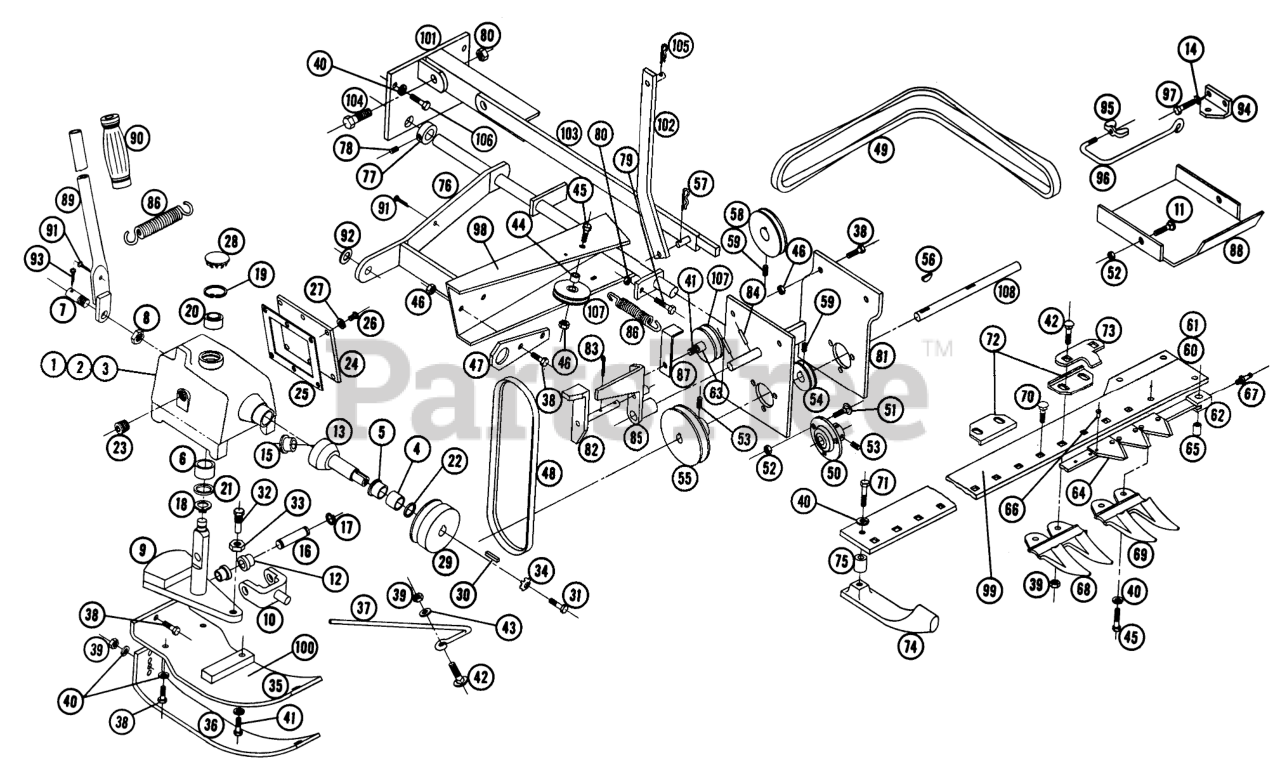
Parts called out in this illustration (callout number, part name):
1	Ass-y Housing Complete-Sickle Drive
2	Ass-y Housings & Bearings
3	Housing
4	Bearing-Bronze Sleeve
5	Bearing-Bronze Sleeve
6	Bearing-Bronze Sleeve
7	Pin
8	Nut, 3/4-16
9	Ass-y. Shaft-Weldment
10	Ass-y. Yoke
11	Bolt-Car. 5/16-18 x 1
12	Bearing-Bronze Sleeve
13	Ass-y. Shaft & Bearing
14	Washer-Lock
15	Bearing-Bronze Sleeve
16	Pin Yoke
17	Snap Ring - Truarc .625 Shaft
18	Snap Ring - Truarc .669 Shaft
19	Snap Ring - Truarc 1.562 Bore
20	Bearing - Ball .687 Shaft
21	Seal 1 1/4 I.D.
22	Seal
23	Plug 1 x 11 1/2 N.P.T.F.
24	Cover Plate
25	Gasket
26	Screw-Rd. Hd. #10-24 x 3/8
27	Lockwasher #10
28	Plug Button
29	Pulley 4 Dia.
30	KEY-STRAIGHT
31	Screw - Nylock 3/8-16 x 7/8
32	Pin Sickle Drive
33	Nut-5/8-18
34	WASHER
35	Ass y. Shoe-Upper-Weldment
36	Shoe-Lower
37	Rod-Grass
38	Bolt 3/8-16 x 1
40	Lockwasher
41	Bolt, 3/8-16 x 1/2
42	Bolt Carriage 3/8-16 x 1
43	Washer
44	SPACER
45	Bolt 3/8-16 x 1
47	Link
48	Belt "A" Sec. 37"
49	Belt "A" Sec. 59"
50	Bearing-Flanged Ball
51	Bolt Hex 5/16-18 x 3/4
52	Nut-Nylok
53	Set Screw 5/16-18 x 5/16
54	Pulley
55	Pulley
56	Key
57	Hairpin
58	Pulley - Engine Drive
59	Set Screw 1/4-20
60	Ass-y. Cutter Bar Complete
61	Ass-y. Bar Guard
62	Ass-y. Knife Bar & Sections
63	Spacer
64	Section
65	Bushing
66	Rivet
67	Zerk
68	Twin Guard
69	Guard Cutter Bar
70	Bolt 3/8-16 x 1
71	Bolt, 3/8 16 x 2
72	Wear Plates
73	Clip, Hold Down
74	Skid
75	Spacer
76	Ass-y. Frame
77	Collar
78	Set Screw 5/16-18 x 3/8 Hex. Soc.
79	Bolt-Hex. 1/2-13 x 2 3/4
80	"V" Belt-Drive
81	Ass-y. Shaft Support
82	Ass-y. Lever
83	Hairpin
84	Roll Pin 3/16 x 1
85	Pedal
86	Spring
87	Clip - Belt
88	Shield - Pulley
89	Ass-y. Lever Lift
90	Grip
91	Cotter Pin
92	Washer
93	Cotter Pin 3/16 x 1
94	Bracket-Travel Hook
95	3/8 NC Wing Nut
96	Hook - Travel Support
97	Bolt 5/16-18 x
98	Decal
99	Decal
100	Decal
101	Ass-y. Plate - Mounting
102	Ass-y. Bar - Lift
103	Ass-y. Bar and Pin - Lower
104	Bolt Hex 1/2-13 x 1 1/2
105	Hairpin
106	Bolt Hex 3/8-16
107	Pulley
108	Shaft
